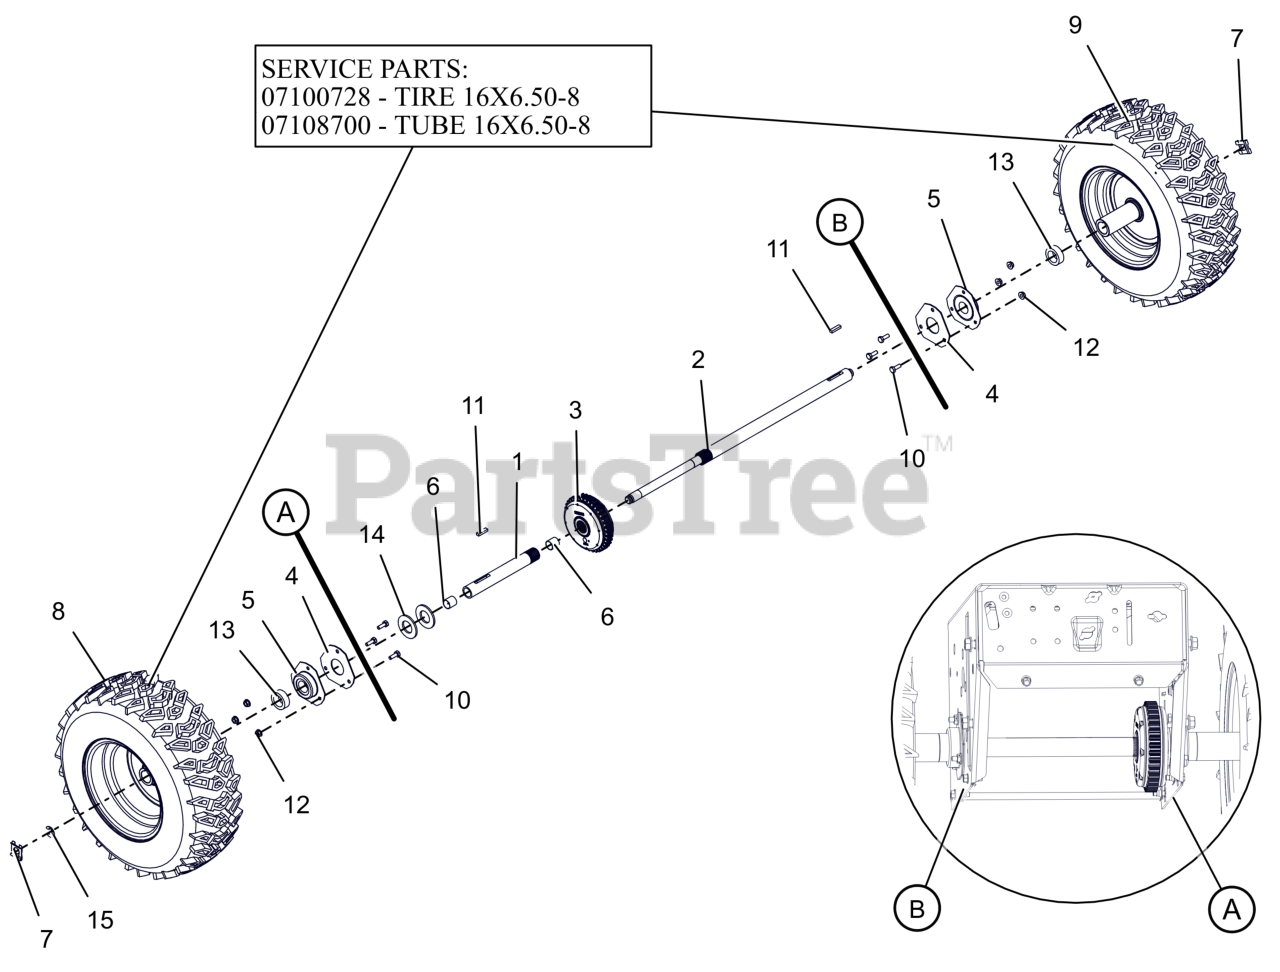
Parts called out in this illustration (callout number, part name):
1	AXLE, SHORT-AUTO W/BUSHINGS
2	AXLE, LONG-PRO AUTO DIFF
3	DIFFERENTIAL, AUTOMATIC
4	PLATE, BEARING SPACER
5	BRG-FLG 1.003/1.000 3 BOLT
6	BSHG-SLV .706X.764X.75 BRZ
7	CLIP, SNAP .625 DIA
8	TIRE/WHEEL,RH 16X6.5-8 DIFF T2
8	TIRE, 16X6.50-8 K478
8	TUBE
9	TIRE/WHEEL,LH 16X6.5-8 DIFF T2
9	TIRE, 16X6.50-8 K478
9	TUBE
10	BLT, HEX .25-20X.75 G5 ZCC
11	KEY-RECT .25X.188X1.00
12	NUT-LK-CTR-FLG .25-20 ZC120
13	SPACER, PRO AXLE BEARING
14	WSHR, FLT 1.062X2.000X.134 ZCC
15	RG-RTNG-EXT .625X.042
